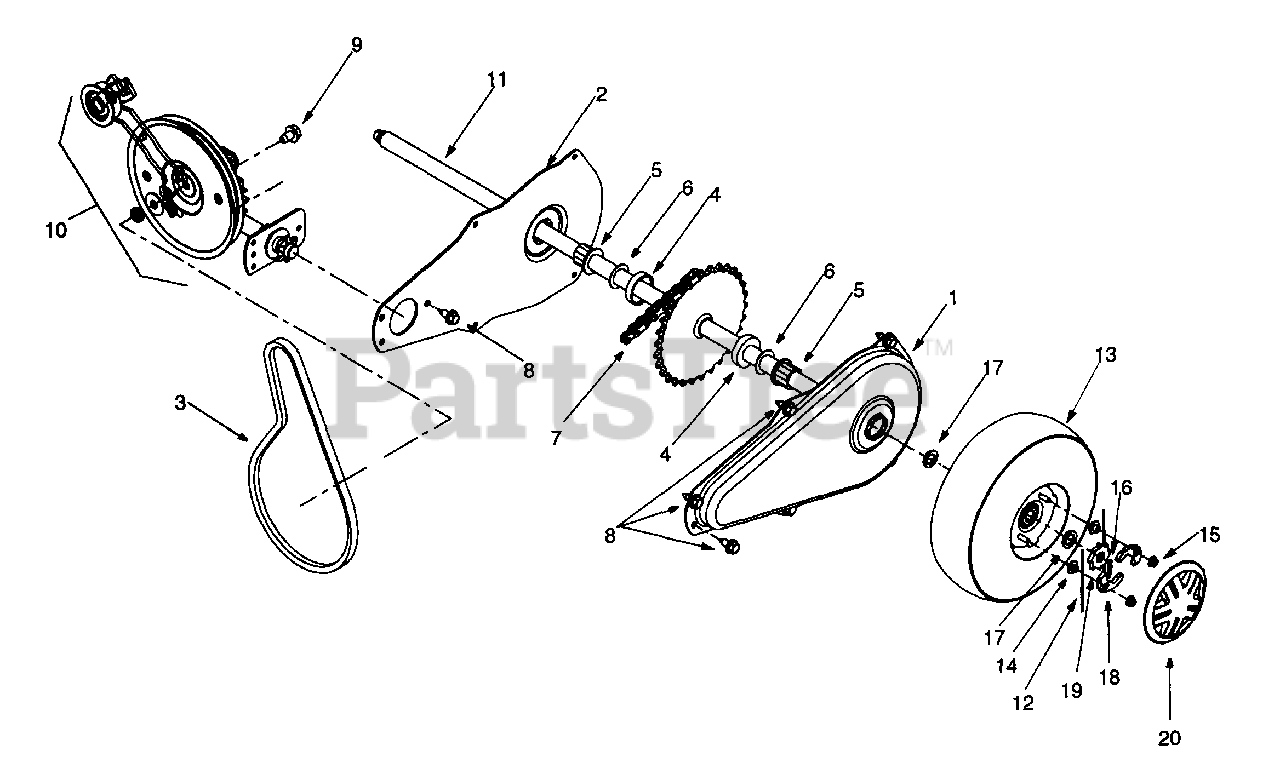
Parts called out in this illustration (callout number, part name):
3	V-Belt
4	Spacer
5	Hex Flange Bearing
6	Flat Washer
7	Chain
8	Hex Washer Screw 1/4-14
9	Hex Washer Screw 5/16
10	Transmission Asm
11	Axle Asm
12	Plastic Spring Ratchet
13	Wheel Complete 10 x 4 x 4
13	Pneumatic Tire 10.0 x 4.0
13	Valve
13	Flange Bearing .632 ID
14	Hex Nut 1/4-20
15	Hex Flanged Lock Nut 1/4-20
16	Cotter Pin
17	Flat Washer 5/8 ID x 1.0 OD
18	Pawl LH .345 ID
18	Pawl RH .345 ID
19	Wheel Ratchet 1.62 OD x .5 serr
20	Hubcap
